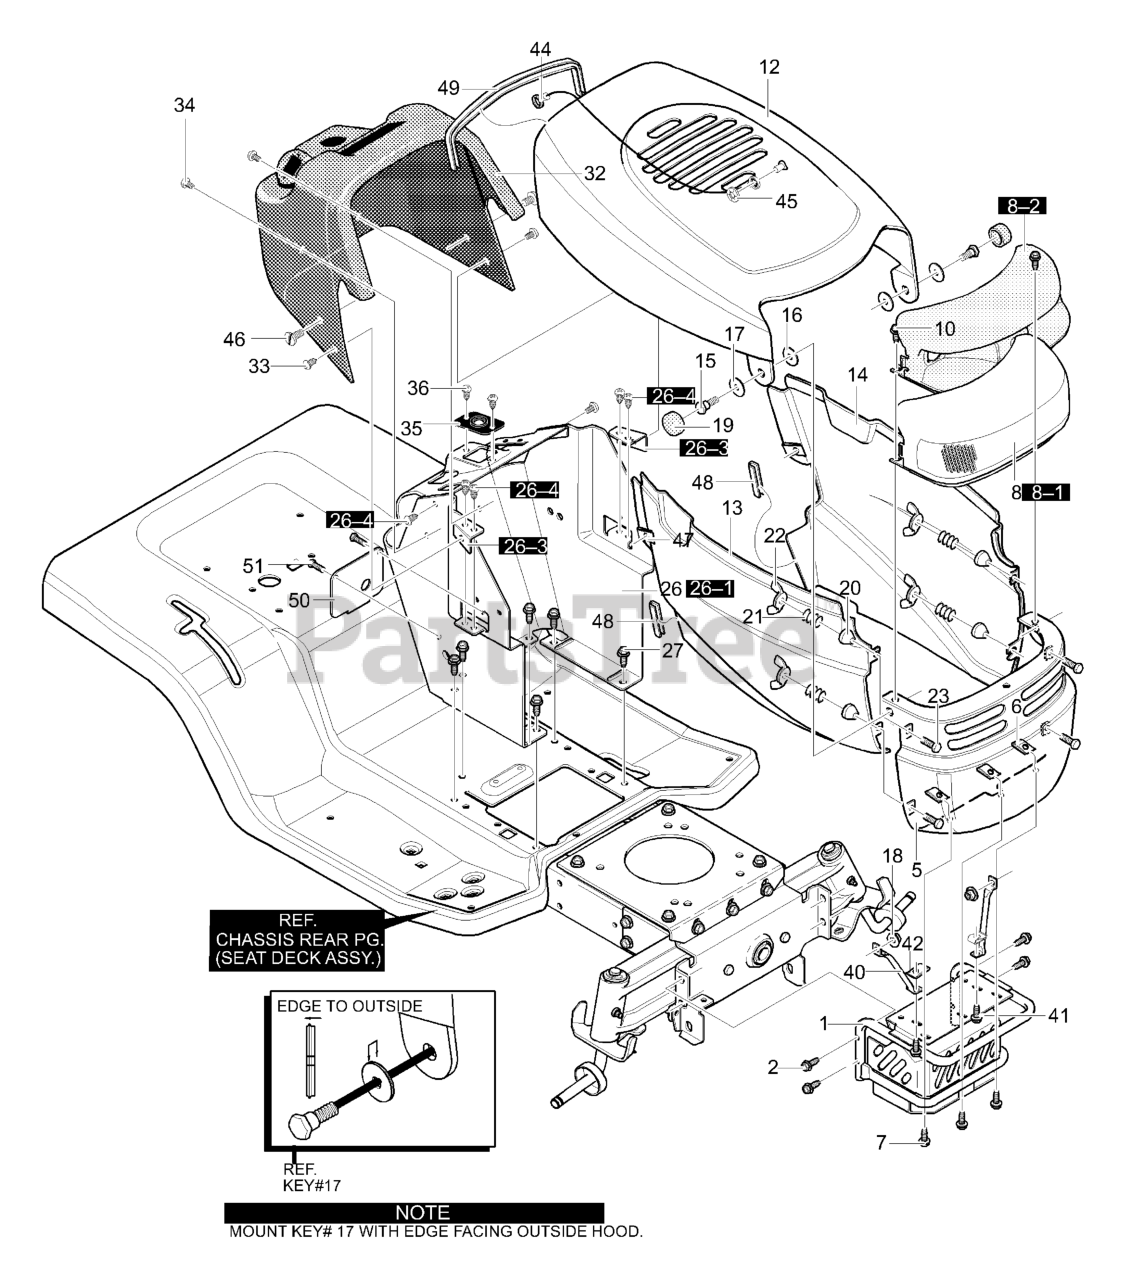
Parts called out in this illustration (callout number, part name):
1	ASSEMBLY, BUMP/GRILLE
2	SCRW5/16-18X1.50
6	NUT, "J" TINNERMAN
7	SCRW,1/4-20X .63
8	ASM., LENS & REFLECTOR
8-2	REFLECTOR
10	SCREW 1/4-14X.50
12	ASM., WELD HOOD H26
13	PANEL, SIDE RH
14	PANEL, SIDE LH
16	WASHER, PLASTIC BLACK
17	PIVOT BASE GREY
18	NUT, 3/8-16
19	PIVOT CAP GREY
20	QUICK RELEASE-CAM
21	SPRING, COMP
22	NUT, WING 1/4-20
23	SCREW, 1/4-20X1.25
26-1	CONSOLE
26-2	BRACKET, LEFT
26-3	BRACKET, RIGHT
27	SCREW 5/16-18X.75
32	DASH, H26 GREY
33	SCREW, 10-24X.50
34	SCREW, 10-24X.50
35	STEERING BRACKET
36	SCREW 1/4-14X.50
40	STRUT, H26 GRILLE
41	SCREW, 1/4-20X .63
42	SPEED NUT
44	LANYARD, H26 HOOD
45	PUSHNUT
46	SCREW, 1/4-20X0.63
47	NUT, "J" TINNERMAN
48	TRIM PIECE PLASTIC GREY
49	TRIM PIECE PLASTIC GREY
50	ACCESS PANEL, W/O SLOT
51	SCREW, 10-24X.50
